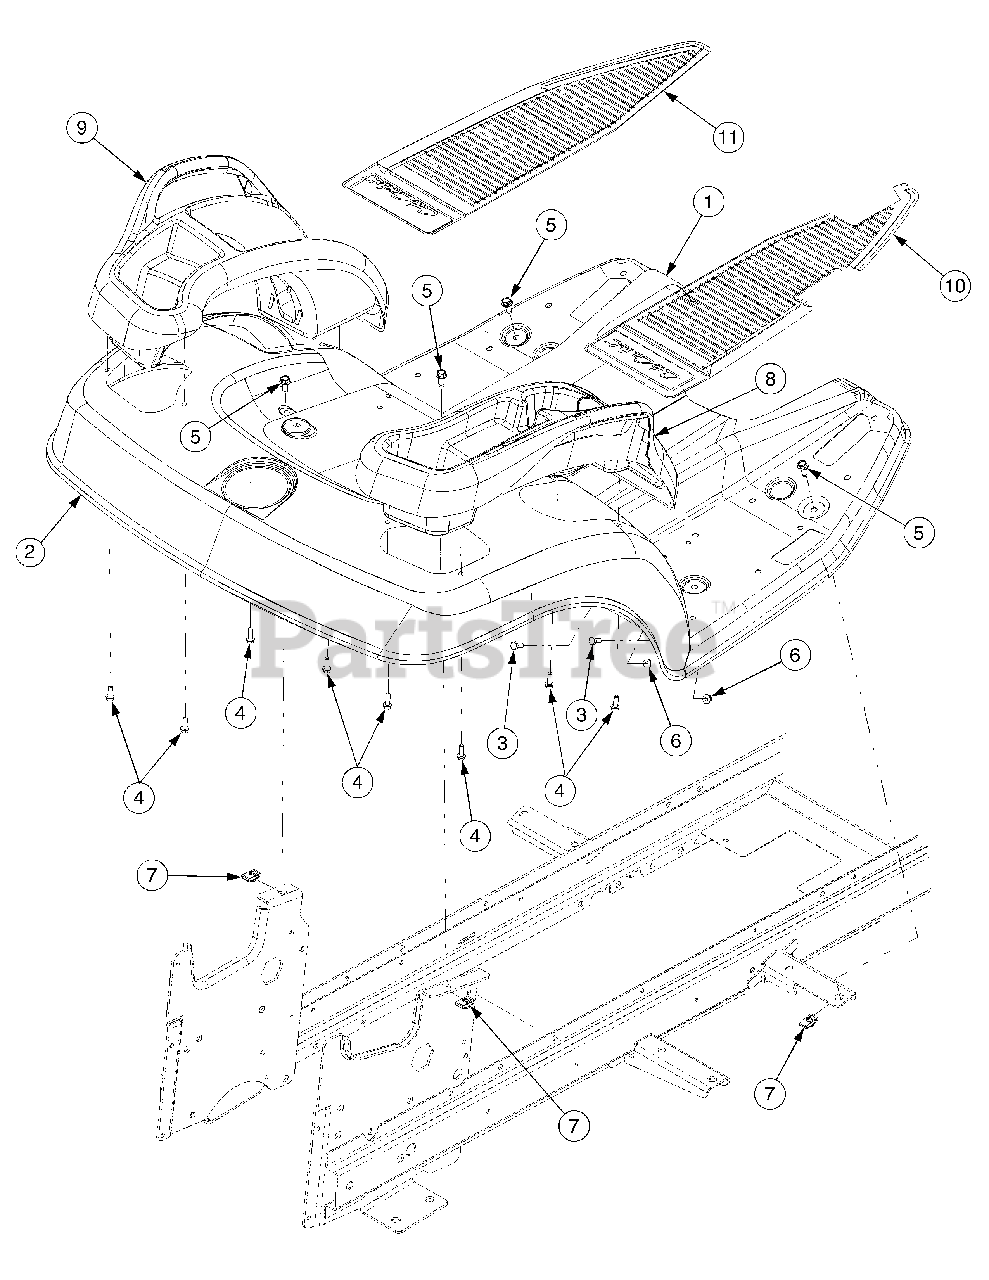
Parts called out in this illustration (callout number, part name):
3	Screw, Hex Cap, 1/4-20 x .75 GR5
4	Screw, 1/4-15 x.750
5	Screw, Hex Wash Hd Tapp 5/16-18 x 1.0
6	Nut, Hex Flange Lock, 1/4-20
7	U-Nut, 5/16-18
8	Cover, Fender RH
9	Cover, Fender LH
10	Pad, RH Foot
11	Pad, LH Foot
